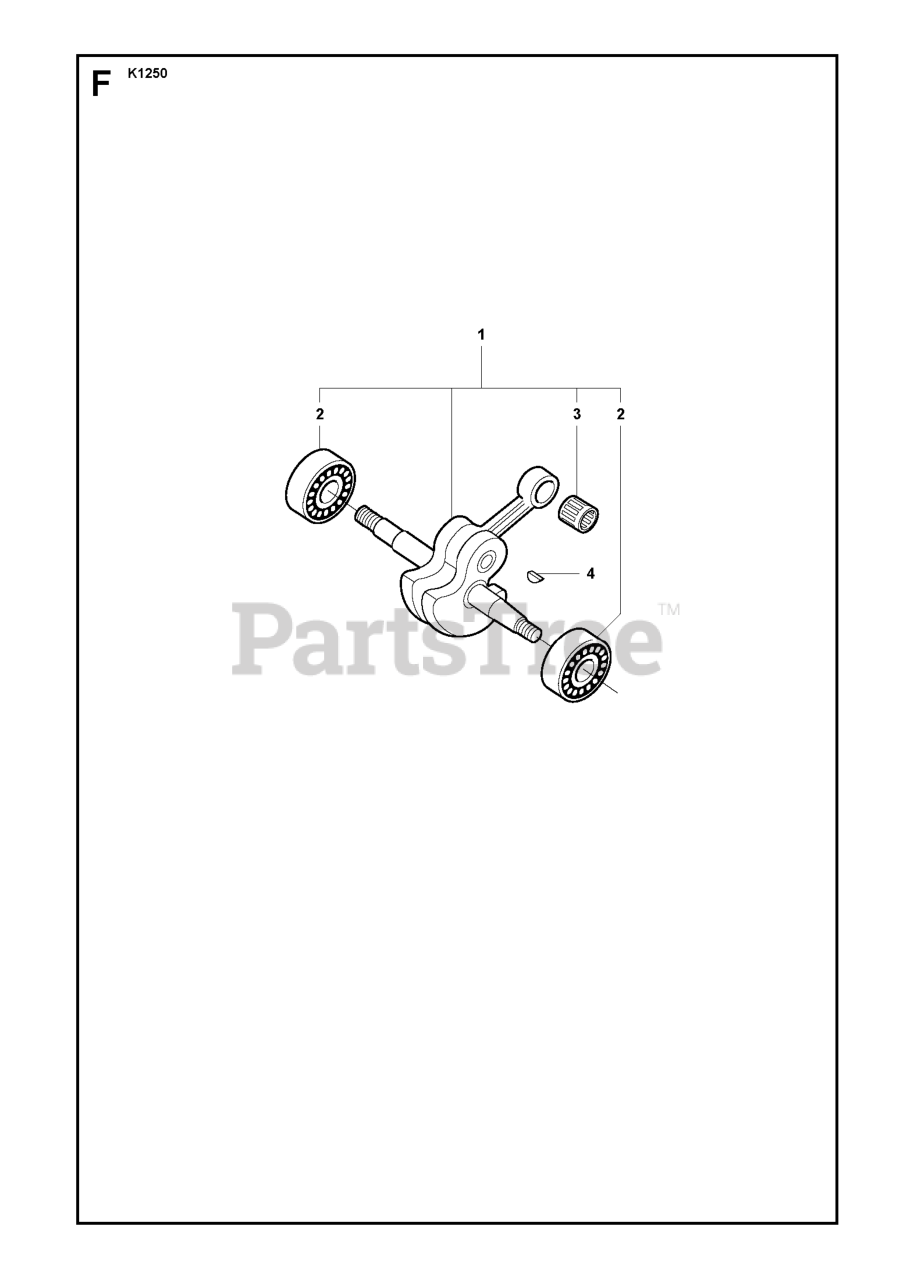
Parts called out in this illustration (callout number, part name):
1	CRANKSHAFT
2	BALL BEARING 6203C3QE6
3	SUPPORT BUSHING
4	WOODRUFF KEY
